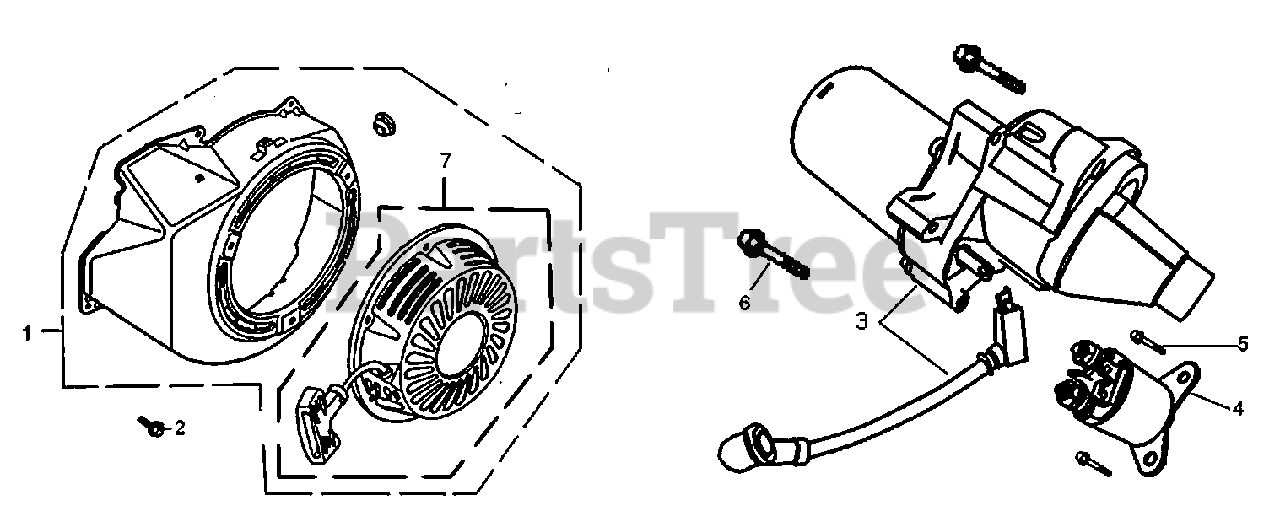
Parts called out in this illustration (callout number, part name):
1	STARTER ASSY. HW
2	BOLT, FLANGE
3	STARTER MOTOR
4	CONTACTOR ASSY.
5	BOLT-WASHER
6	BOLT, FLANGE
7	ASSY, RECOIL STARTER HW (W/O BLOWER HOUSING)
